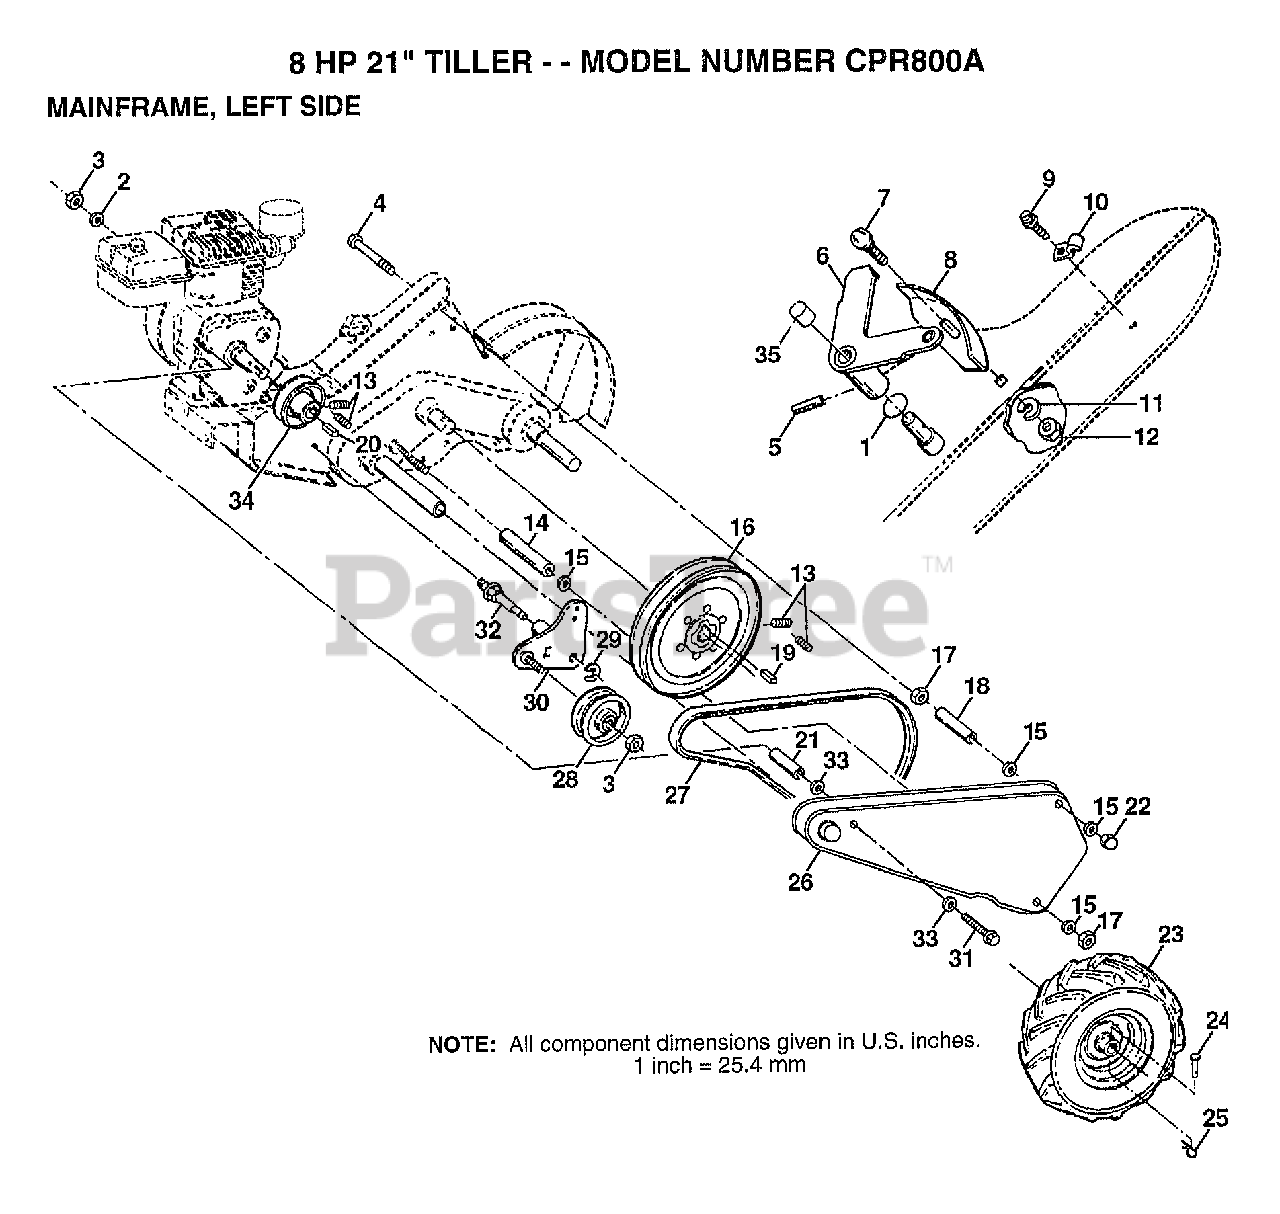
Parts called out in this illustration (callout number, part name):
1	O-RING TI
2	LOCKWASHER
3	NUT.HEX.3/8-16UNC
4	BOLT TI
6	LEVER ASM CRT
7	BOLT
8	PANEL TI
10	CONDIUT CLIP T
11	LOCKWASHER
13	SET SCREW
14	SPACER TI
15	WASHER
16	"SHEAVE 10"" CRT"
17	NUT.HEX.5/16-18
18	SPACER TI
19	KEY T
20	KEY TI
21	SPACER.SPLIT
22	NUT TI
23	TIRE TI
23	RIM.16X4X8.WHT
24	RIVET.PAN HD.1.75
25	SPRING.RETAINER
26	GUARD.BELT.GREY
27	BELT.DRIVE
29	KLIP RING
31	BOLT1/2-20UNF2.75
32	SHAFT.IDLER
34	SHEAVE CRT
35	CAP PLUNGER BLACK
